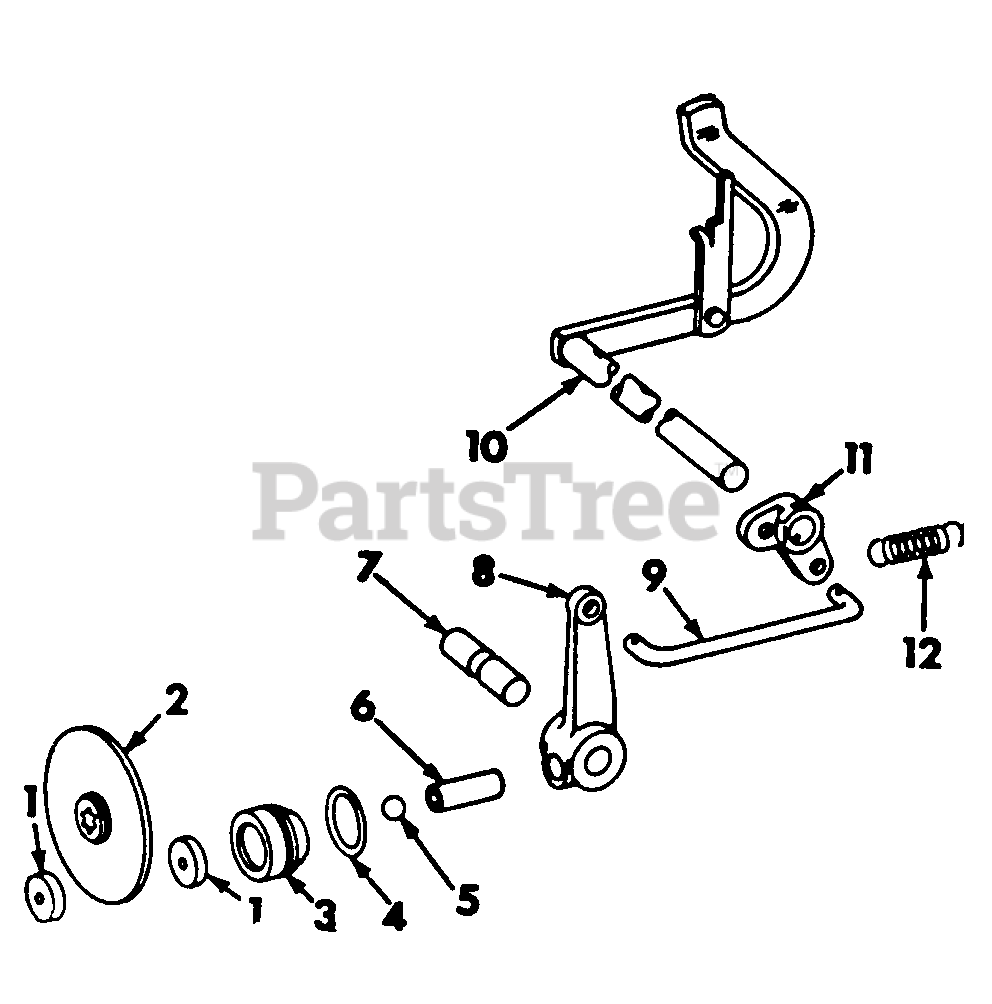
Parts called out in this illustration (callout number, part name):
1	Disc, Brake Lining
2	Disc Assy, Brake
3	Retainer, Brake Lining
4	O-Ring, 1-3/16 X 1-3/8 X 3/32
5	Ball, 9/16 Cr Stl
6	Rod, Brake Push
7	Pin, Brake Lever Pivot
8	Lever, Brake
10	Pedal Assy, Clutch & Brake
11	Arm, Clutch & Brake Pedal
12	Spring, Clutch Pedal Return
